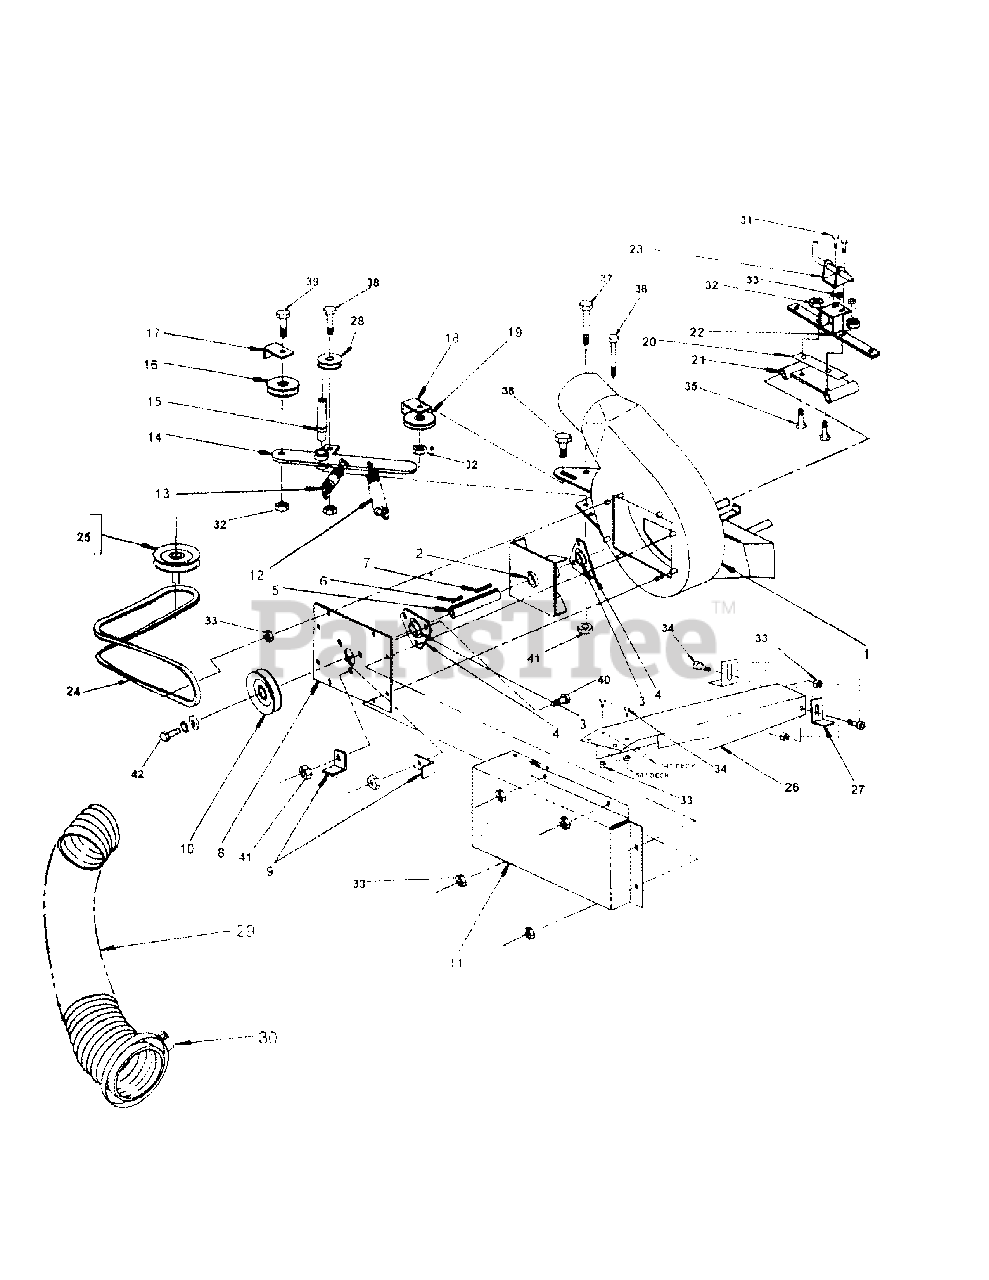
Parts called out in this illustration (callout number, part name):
1	Blower housing
2	Fan
3	Bearing
4	Flange - bearing (set of 2)
5	Fan shaft
6	1/4" x 3/4" key-way
7	1/4" x 1 1/4" key-way
8	Back canister cover
9	Fan pulley belt bracket
10	Fan drive pulley
11	Blower Belt cover
12	7/8 x 6 Spring
13	13/16 x 3-1/8 Spring
14	Idler arm
15	Idler arm pivot
16	Flat Idler pulley
17	Lower pulley bracket
18	Upper pulley bracket
19	V-Idler pulley
20	Upper mounting bracket spacer
21	Lower mounting bracket
22	Upper mounting bracket
23	Spring Latch
25	Drive pulley
26	Belt Guard
27	Belt Guard Leg
28	2.5" V-Idler Pulley
29	43" Urethane Hose
30	Hose Clamp
31	1/4" - 20x3/4" Hex head
32	3/8" - 16 serrated flange nut
33	1/4" - 20 serrated flange nut
34	1/4" - 20 x 1/2" hex head
35	3/8" - 16 x 1" Carriage bolt
36	1/4" - 20 x 4 1/2" hex head
37	3/8" - 16 x 4 1/4" hex head
38	3/8" - 16 x 1 1/2" Hex head
39	3/8" - 16 x 1 3/4" hex head
40	5/16" - 18 x 3/4" hex head
41	5/16" - 18 serrated flange nut
42	5/16" - 24 x 1" Hex head
